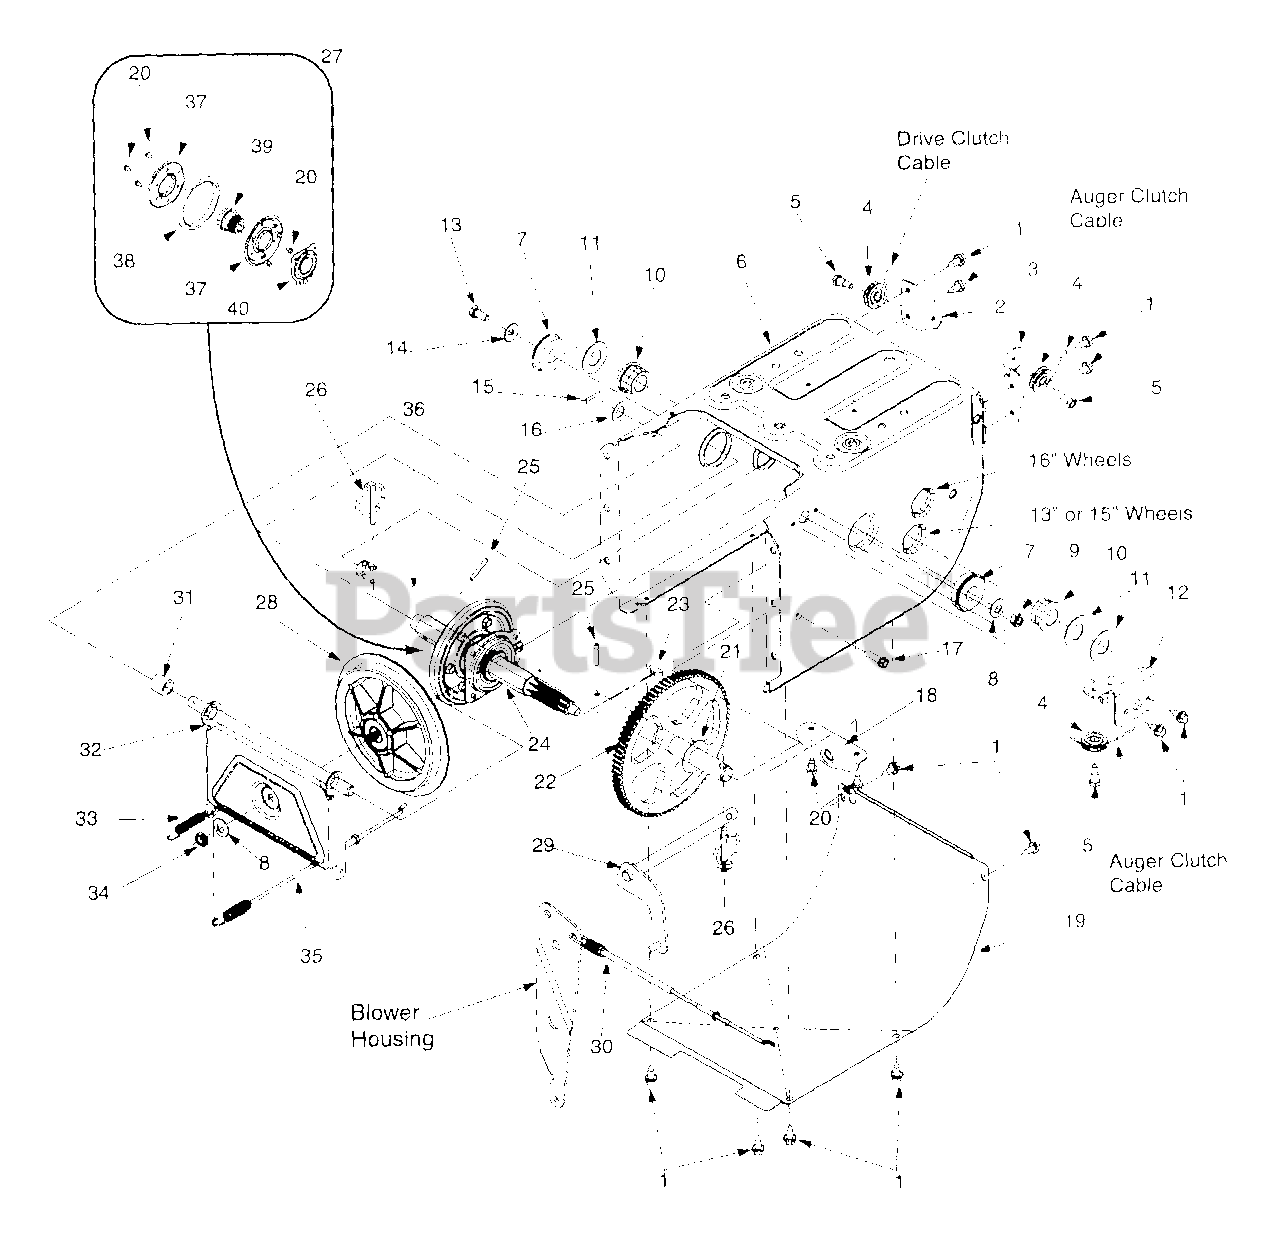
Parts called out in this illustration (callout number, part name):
1	Hex Screw
5	Hex Screw 1/4-28
8	Bell Washer
9	Lock Jam Nut
10	Hex Flange Bearing
11	Flat Washer
14	Bell Washer .340 I D x .872 OD
15	Cotter Pin
16	Flat Washer .536 ID x .930 OD
17	Hex Washer Screw 1/4-20
21	Flat Washer .760 ID x .50 OD
24	7-Tooth Shaft
25	Roll Pin
26	Klik Pin
27	Friction Wheel Assembly
28	Friction Disc Wheel
29	Wheel Shift Rod Assembly
30	Drive Cable
31	Spacer
34	Jam Nut 3/8-24
35	Drive Cable
36	Axle 13" Wheels
37	Friction Plate
38	Friction Wheel Rubber
39	Friction Wheel Hub
40	Friction Wheel Bearing
